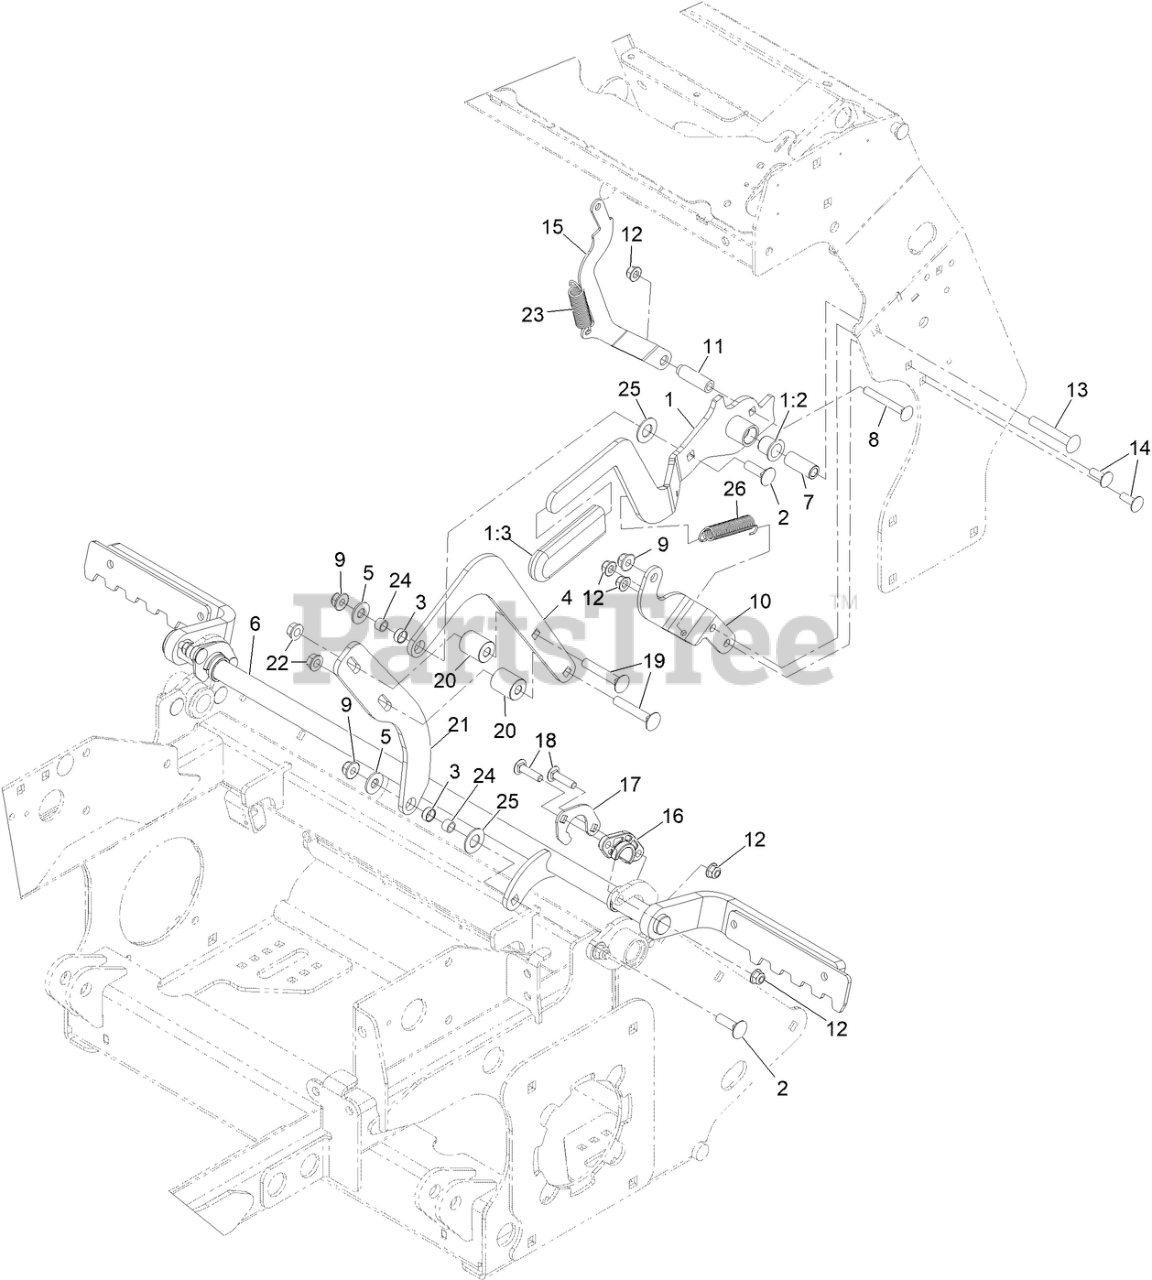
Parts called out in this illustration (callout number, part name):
1	ASM-HANDLE BRAKE
1:2	BUSHING-FLANGE
1:3	GRIP-LEVER
2	BOLT-CARR
3	BEARING-SLEEVE
4	LINK-BRAKE UPPER
5	WASHER-FLAT
6	ASM-Brake Shaft [black]
7	SPACER-PIVOT
8	SCREW-CARR
9	NUT-HF, NI
10	BRACKET-BRAKE LEVER SUPT
11	SPACER-.31 X 1.25 YZ
12	NUT-HF, NI
13	SCREW-CARR
14	BOLT-CARR
15	Link-Brake Control Lock
16	BEARING-FLANGE
17	SUPPORT, BEARING
18	SCREW-CARR
19	Bolt-Carriage 3/8-16 X 2 1/4
20	SPACER-.39 IDX1.0 ODX1.2 L
21	LINK - LOWER BRAKE
22	NUT-HHF, WHIZ
23	SPRING-EXTENSION
24	SPACER-BRAKE PIVOT
25	WASHER-PLASTIC
26	SPRING-EXTENSION
